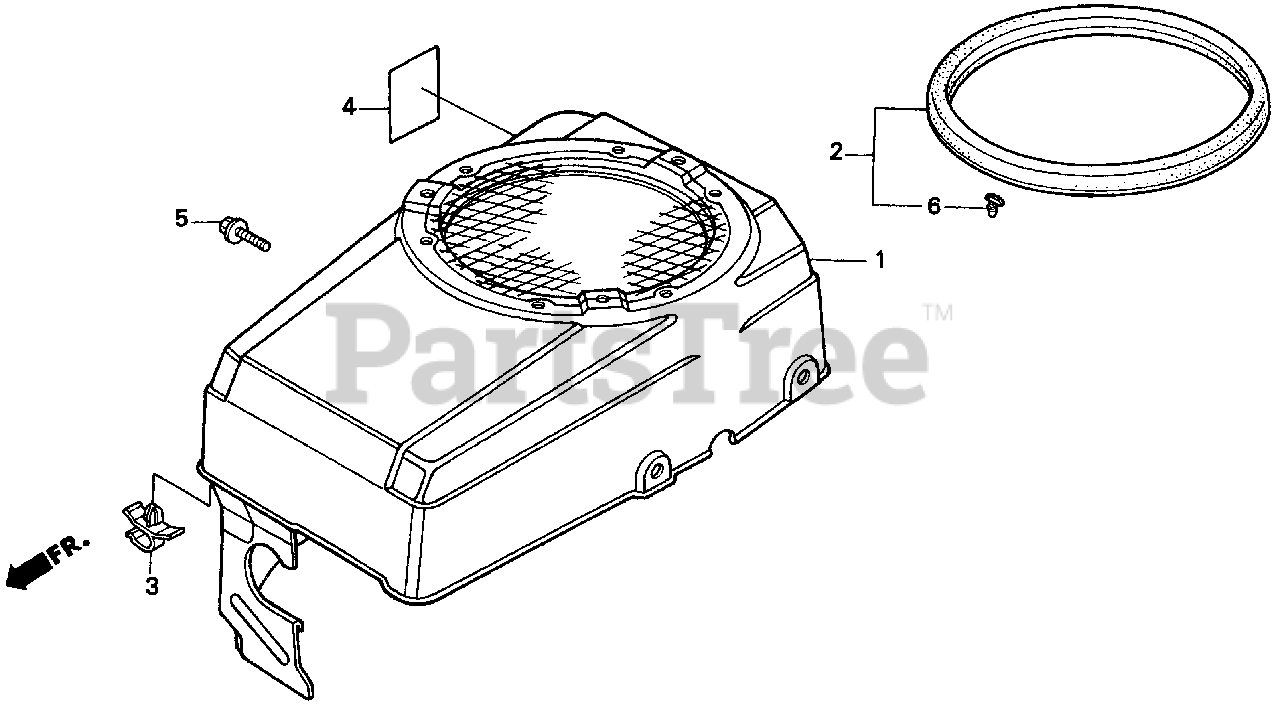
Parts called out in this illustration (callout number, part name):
1	COVER, FAN
2	SEAL, LAWN COVER
3	CLIP, WIRE HARNESS
4	MARK, OIL CAUTION
5	BOLT, FLANGE (6X12) (CT200)
6	CLIP, CANOE
